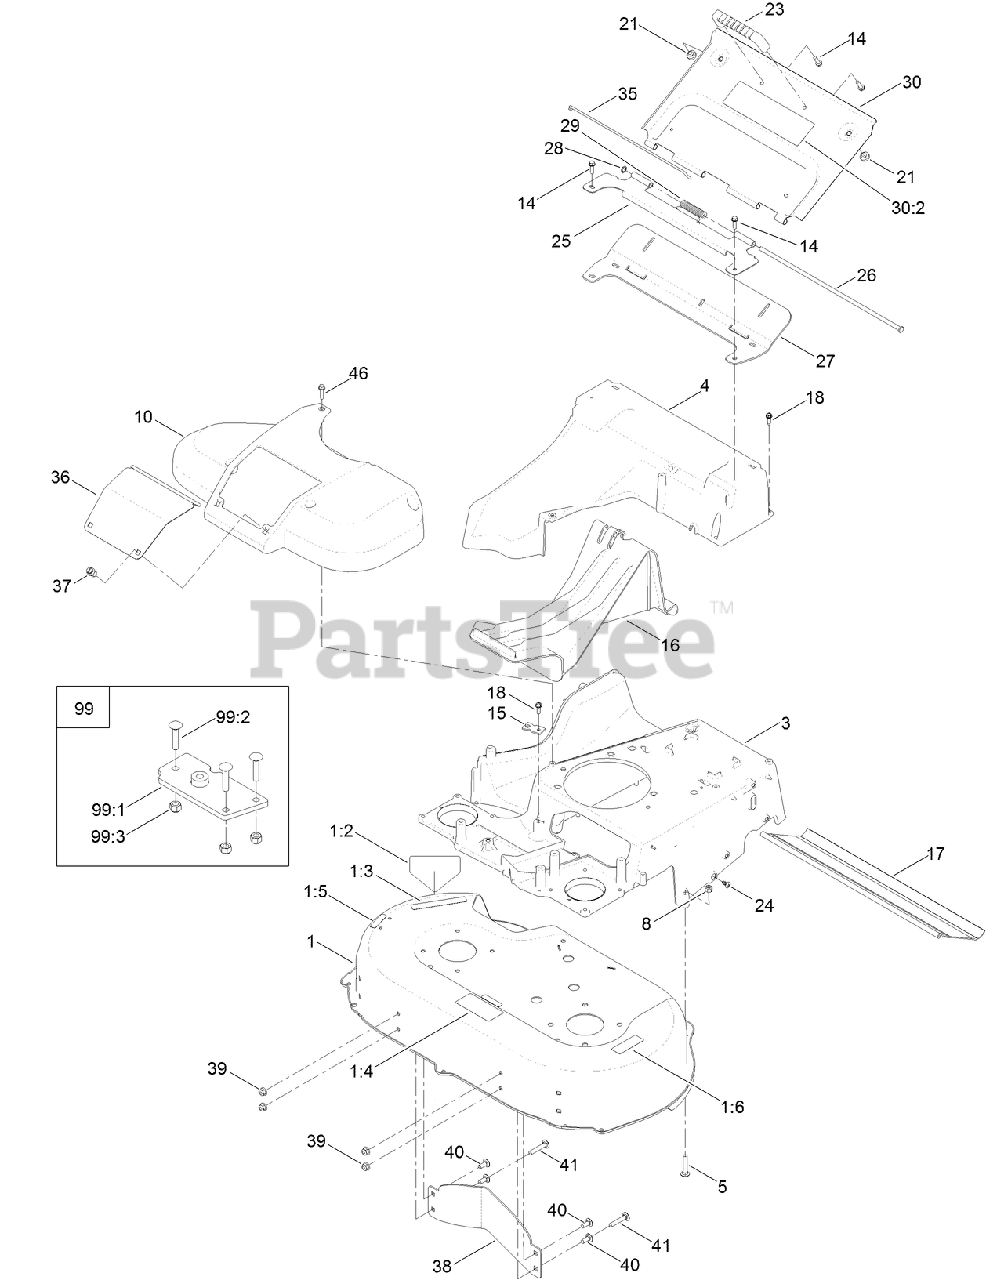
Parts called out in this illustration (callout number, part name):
1	DECK-30 INCH
1:2	DECAL-DANGER
1:3	DECAL-DANGER
1:5	DECAL-WARNING
1:6	DECAL-WARNING, BLOCK
5	BOLT-CAR
8	NUT-LOCK, NI
10	COVER-BELT
14	SCREW-HWH
16	PLUG-MULCH
17	SHIELD-TRAILING
18	SCREW-HWHTF
21	BUMPER
23	HANDLE-DOOR
24	SCREW-PTH
25	BRACKET-HINGE
26	PIN-HINGE
27	SEAL-DOOR
28	RING-RETAINING
29	SPRING-TORSION, COVER
30	REAR DOOR ASM
30:2	DECAL-WARNING
35	CLIP-SEAL
36	DOOR-ACCESS
37	FASTENER
38	BAFFLE-CONTROL
39	NUT-HF, NI
40	SCREW-CARR
41	SCREW-CARR
46	SCREW-HWHTF
99:1	PLATE-FRAME
99:2	SCREW-CARR
99:3	NUT-LOCK, NI
